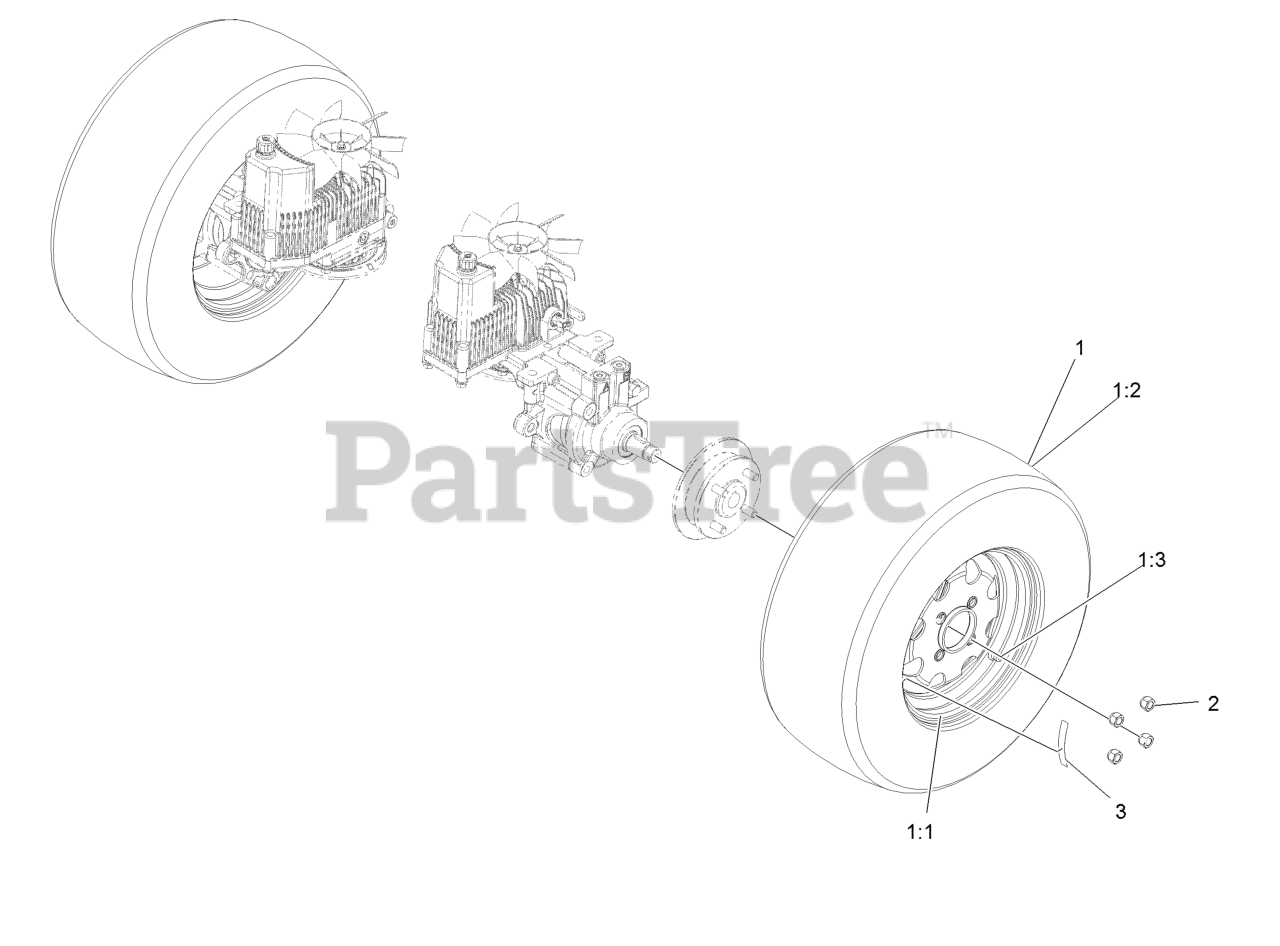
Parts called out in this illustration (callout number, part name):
1	Wheel And Tire ASM
1:1	Rim ASM
1:2	Tire
1:3	Stem-Valve
2	Nut-Lug 1/2-20
3	Decal-Torque, Wheel Hub Lug
